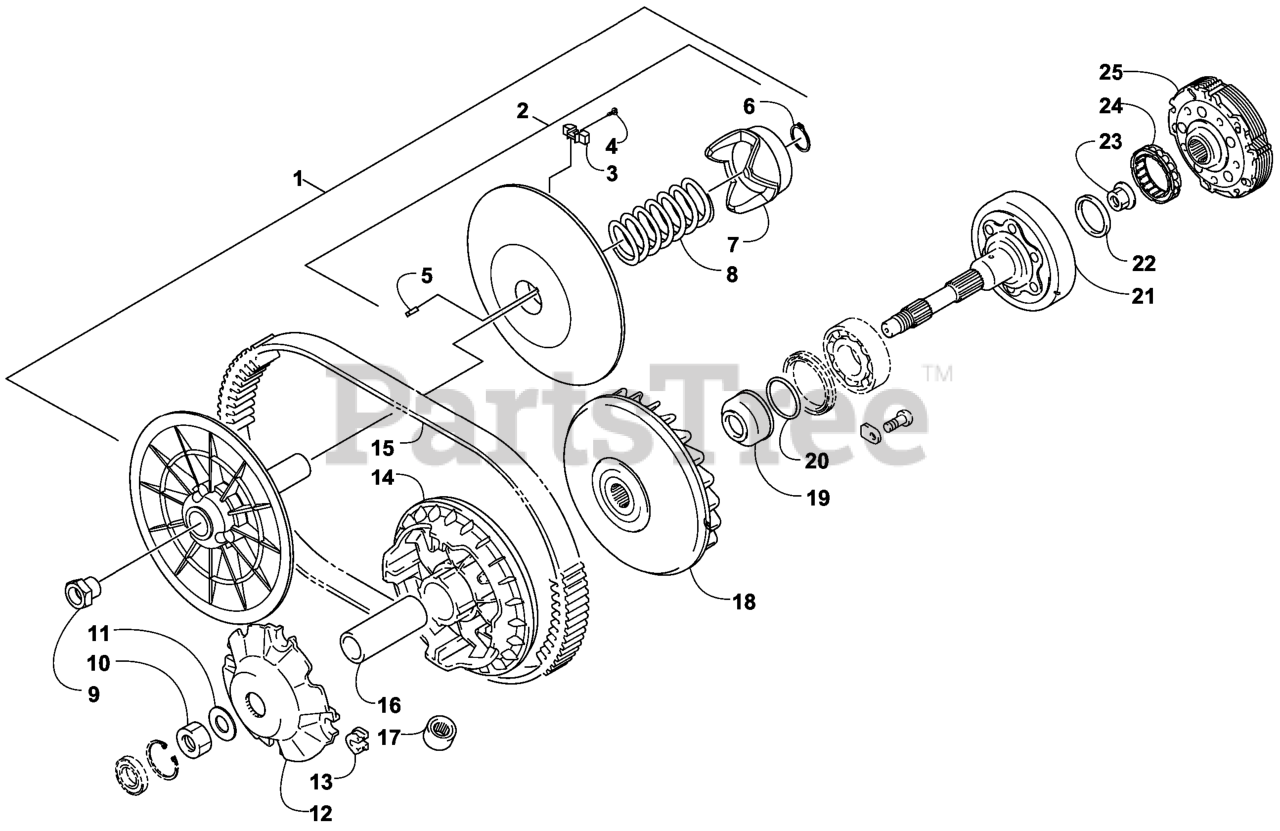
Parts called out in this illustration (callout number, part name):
2	Pulley, Driven - Uncalibrated
3	SHOE-CAM, DRIVEN PULLEY
4	SCREW-CAM SHOE
6	RING-SNAP, EXTERNAL
7	CAM-DRIVEN CLUTCH, 45 DEG
8	SPRING-DRIVEN CLUTCH
10	NUT-HH, COUNTERSUNK
13	DAMPER-MOVABLE DRIVE-Z
14	SHEAVE-MOVABLE DRIVE
15	BELT-DRIVE
16	SPACER-MOVABLE DRIVE FACE
17	ROLLER-MOVABLE DRIVE
18	SHEAVE-STATIONARY, DRIVE
19	SPACER-FIXED DRIVE
21	CLUTCH-HOUSING, 6-PLATE A
22	SEAL-DRUM SHAFT
23	NUT-HHF, CCW
25	CLUTCH-CENTRIFICAL, 6 PLA
